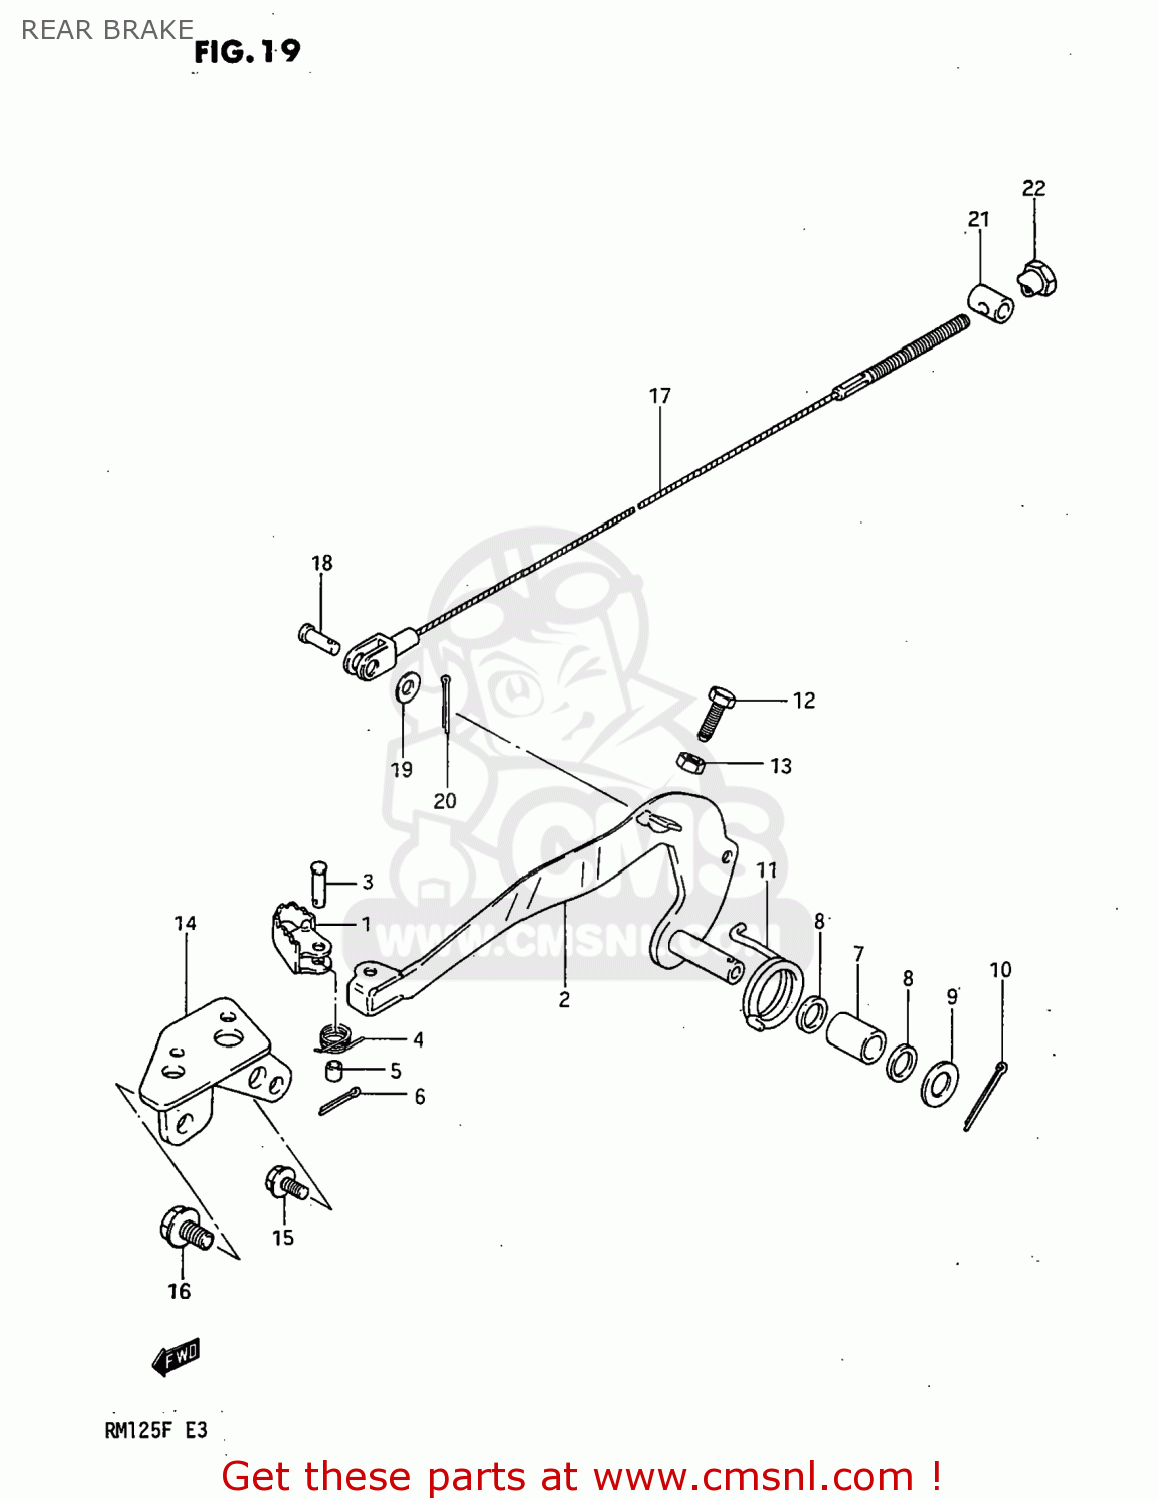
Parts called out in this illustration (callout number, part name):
1	PEDAL,BRAKE
2	ARM,BRAKE PEDAL
3	PIN
4	SPRING
5	SPACER(9.2X9X6.5)
6	PIN
7	BUSHING
8	O RING(D:2.2,ID:11.8)
9	WASHER
10	PIN 30X20
11	SPRING
12	SCREW(6X23)
13	NUT
14	PROTECTOR,BRAKE
15	BOLT
16	BOLT 8X12
17	CABLE ASSEMBLY,REAR BRAKE
18	PIN(L:17.5)
19	WASHER
20	PIN 20X20
21	PIN
22	NUT (6MM)
